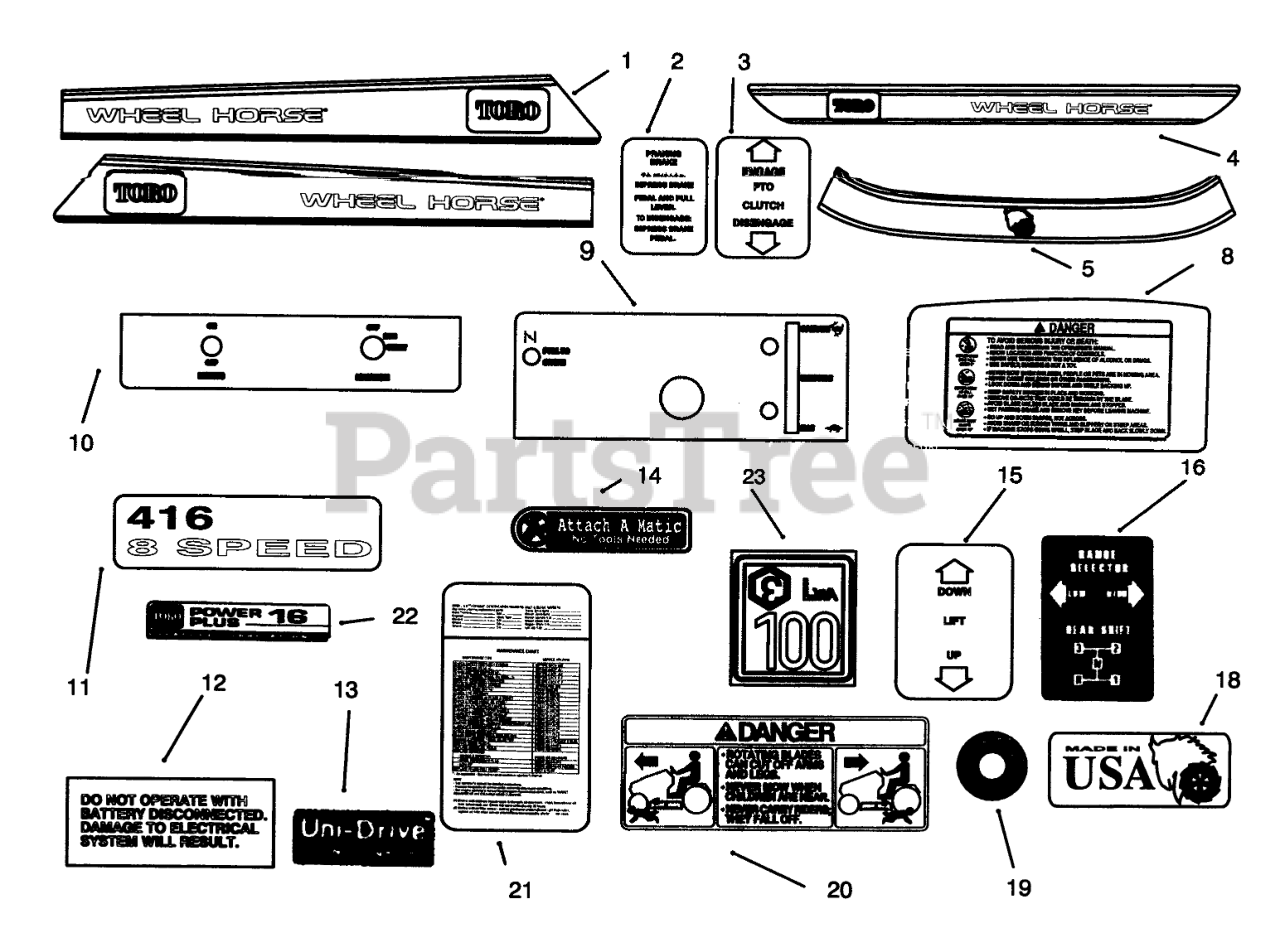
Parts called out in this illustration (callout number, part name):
1	DECAL - RH HOOD TOP
2	DECAL-PARKING, BRAKE
3	DECAL PTO CLUTCH
4	DECAL - REAR FENDER
5	DECAL-FRONT HOOD, TOP
8	DECAL - DANGER
9	DECAL-LOWER DASH
10	Decal-Black Plate
11	DECAL - MODEL 416-8
12	DECAL ELECT SYSTEM
13	Decal-Unidrive
14	DECAL-ATTACH A-MATIC
15	DECAL-LIFT
16	DECAL-SHIFT PATTERN
18	DECAL - USA
19	Decal-Air Cleaner
20	DECAL-DANGER
21	Decal-Maintenance
22	DECAL-PWR PLUS 16 PL
23	DECAL-EUROPE
